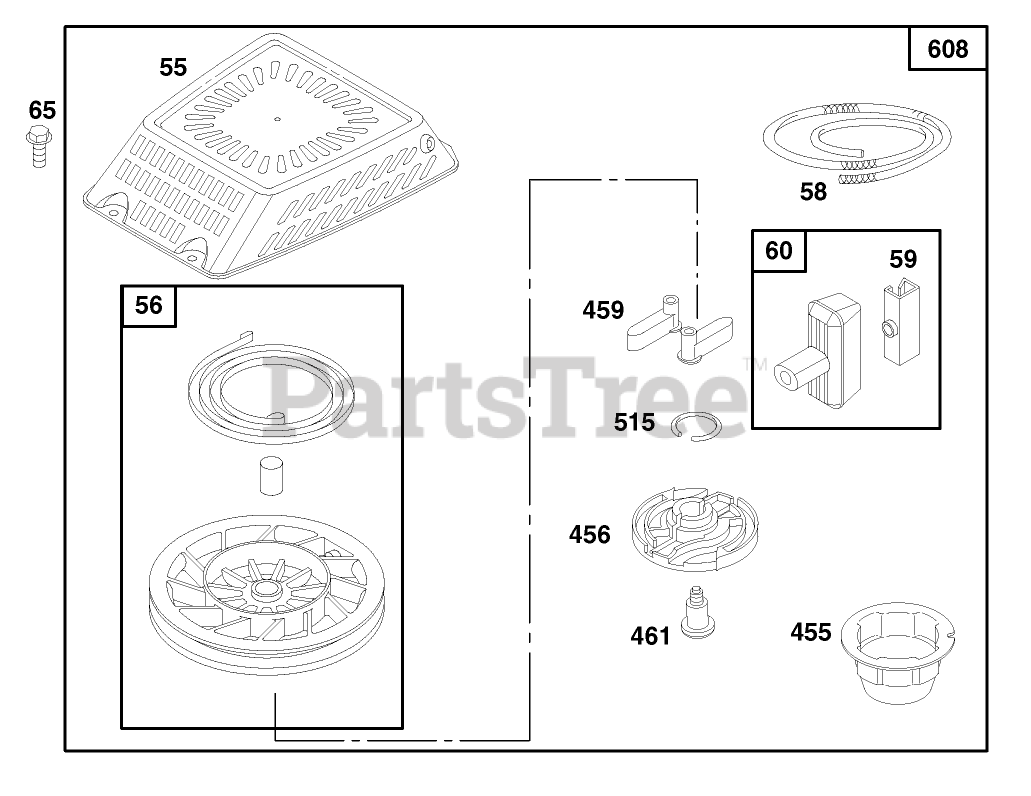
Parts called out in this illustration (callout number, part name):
56	PULLEY-STARTER, REWIND
58	ROPE-STARTER
59	INSERT-HANDLE, REWIND
455	CUP - STARTER
456	RETAINER-STARTER, REWIND
459	PAWL-STARTER
515	SPRING-TORSION
608	BRIGGS #498146
